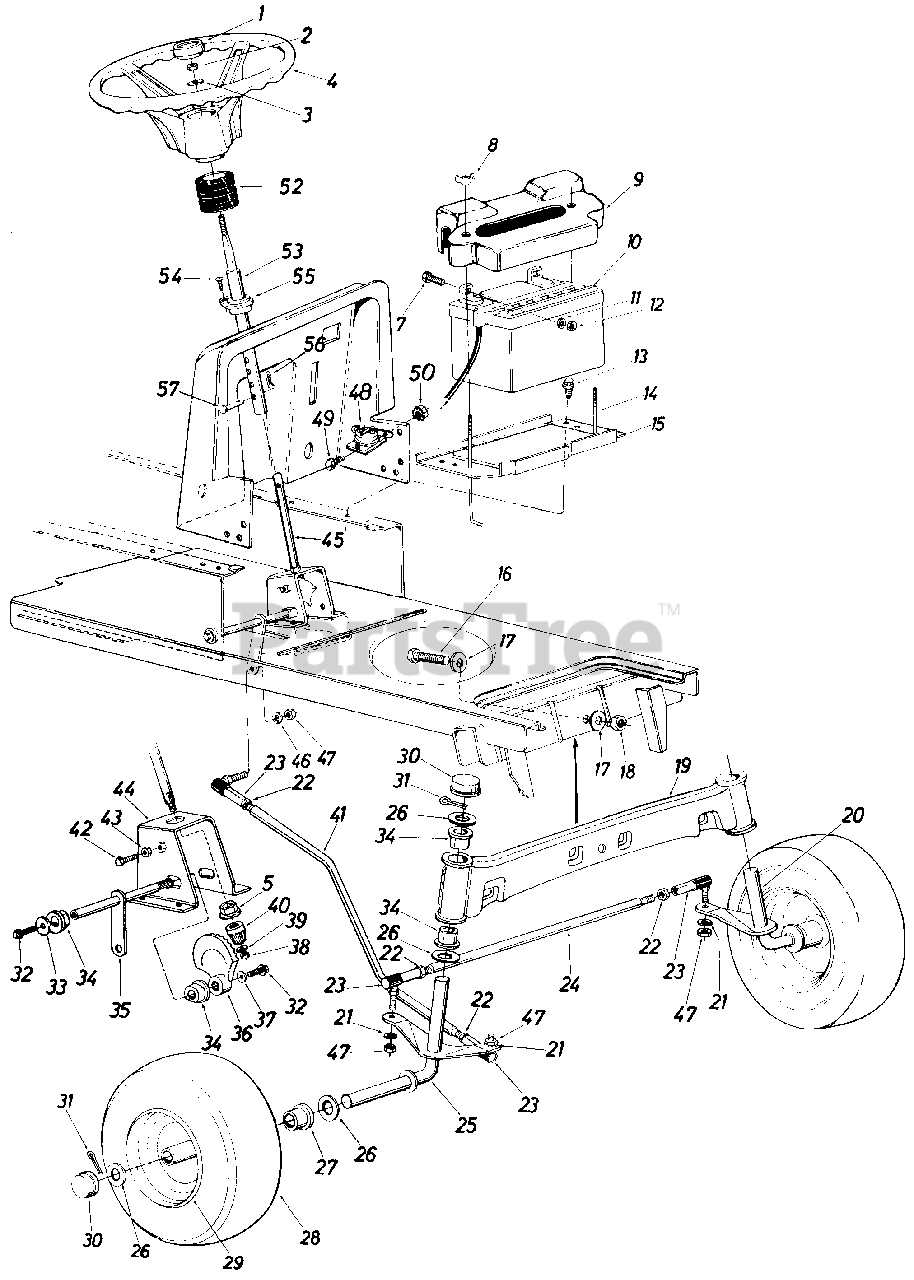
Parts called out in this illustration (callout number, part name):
1	Steering Wheel Cap
2	Hex Cent. L-Nut 5/16-18 Thd.
3	Bell-Wash. 5/16" I.D. x .87" O.D. x .060
4	Steering Wheel
7	Hex Scr. 1/4-20 x .62" Lg.
8	Wing Nut Plastic 1/4-20 Thd.
9	Battery Cover
10	12-V Battery
11	L-Wash. 1/4" Scr.
12	Hex Nut 1/4-20 Thd.
13	Hex Thd. Rolling Scr. 1/4-20 x . 50" Lg.
14	Battery Hold Down Rod
15	Battery Plate
16	Hex Scr. 5/8-18 x 2.50" Lg.
17	Flat Wash. .66" I.D. x 2.25" O.D. x .17
18	Hex Cent. L-Nut 5/8-18 Thd.
19	Front Pivot Bar Ass'y.
20	Front Axle Ass'y. L.H.
21	L-Wash. 3/8" Scr.
22	Hex Jam Nut 3/8-24 Thd.
23	Ball Joint Ass'y.
24	Tie Rod
25	Front Axle Ass'y. R.H.
26	Fl-Wash. .780 I.D. x 1.59 O.D.
27	Flange Bearing
28	Front Wheel Ass'y. Comp.
29	Front Wheel Rim Only
30	Dust Cover
31	Cotter Pin 5/32" Dia. x 1.00" Lg.
32	Hex Scr. 3/8-24 x .75" Lg. Grade 5
33	Fl-Wash. 3/8 I.D. x 1.25 O.D. x .090
34	Flange Double "D" Brg. .753 I .D.
35	Steering Arm Shaft Ass'y.
36	Side Gear Steering
37	Bell-Wash. 3/8 I.D.
38	Hex Cent. L-Nut 5/16-24 Thd.
39	Fl-Wash. 5/16" I.D. x .62 O.D. x .059
40	Pinion Gear Steering
41	Drag Link
42	Hex Nylon Scr. 3/8-16 x 1.25" Lg.
43	Hex Nut 3/8-16 Thd.
44	Steering Gear Sup. Ass'y.
45	Lower Steering Shaft
46	L-Wash. 3/8" Scr.
47	Hex Nut 3/8-24 Thd.
48	Solenoid
49	Hex Bolt 1/4-20 x .50" Lg.
50	Hex Sems Nut 1/4-20 Thd.
52	Steering Bellow
53	Upper Steering Shaft
54	Oval Hd. Cr.-Sunk Scr. #10 x 5/8" Lg.
55	Fl-Bearing .89" I.D. x 1.36" O.D.
56	Hairpin Cotter
57	Clevis Pin
